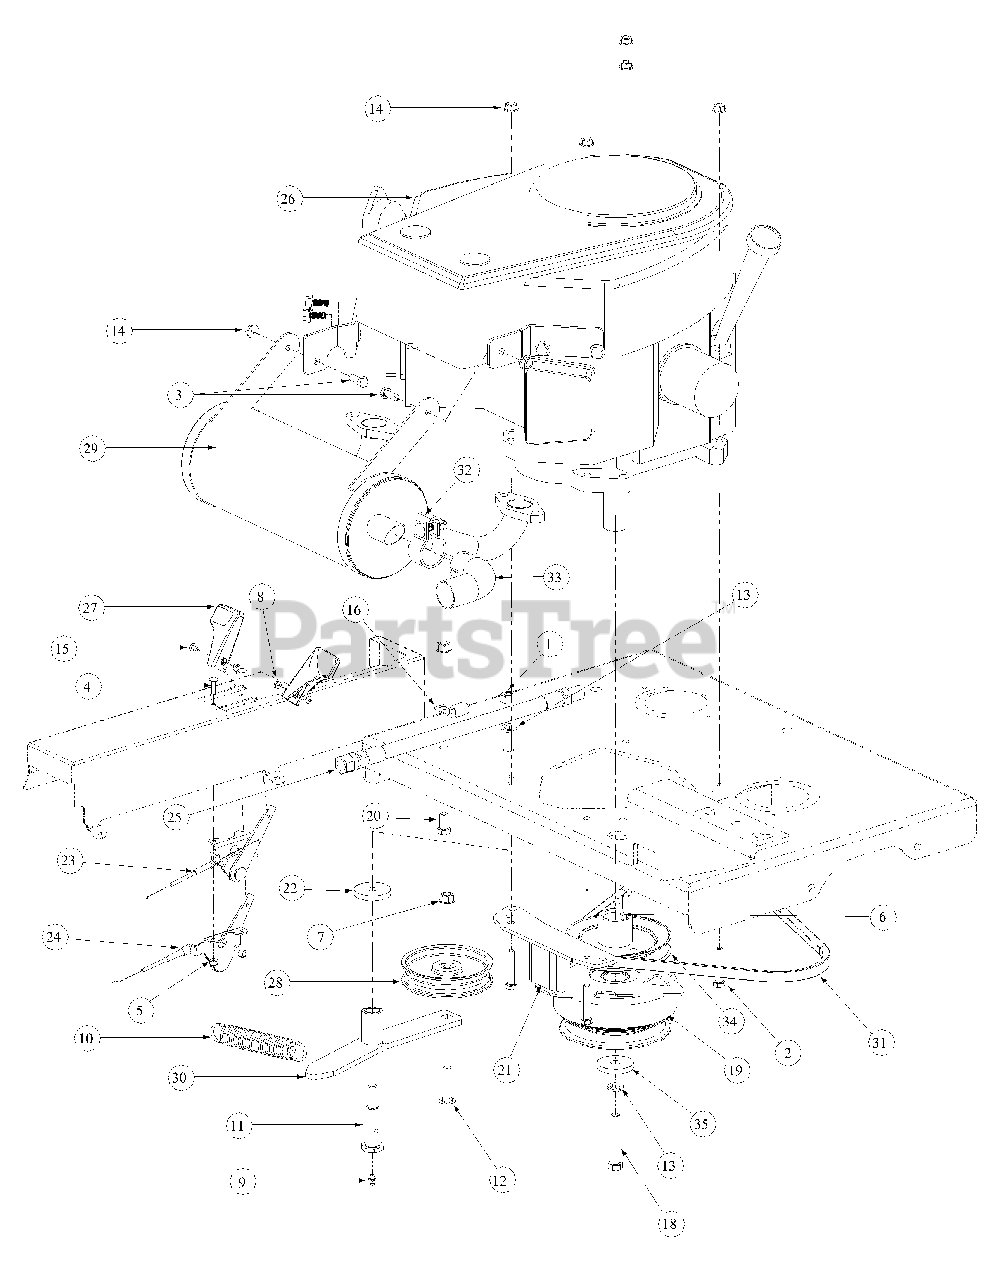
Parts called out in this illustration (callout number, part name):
1	Hex Nut, 7/16-14
2	HHCS, 5/16-18, 1-3/4
3	Hex Cap Screw, 5/16-18 x 3/4
4	Round Hd. Machine Screw, 10-32 x 3/4
5	Lock Nut, Nylon Insert, 10-32
6	Key, 1/4 x 1/4 x 3
7	Flange Lock, Hex Nut, 3/8-16
8	Nut Washer, W/Star, 8-32
9	Grease Fitting, 1/4-28 x 3/16
10	Extension Spring, 1.0 OD x 5.125
11	Shoulder Screw, 7/16-14
12	Hex Carriage Screw, 3/8-16, 1.75
13	Lock Washer, 7/16
14	Hexflange Lock Nut, 5/16-18
15	Machine Screw, 8-32, .375
16	Clip, Heat Shield Cable
18	Capscrew, 7/16-20 x 2.50
19	Clutch Brake, 1.125 ID
20	Hex Cap Screw, 3/8-16, .750
21	Retainer Clutch Assembly, Ogura
22	Flat Washer, 7/16 ID x 1.75 OD x .25
23	Choke, Control Cable, 43.0
24	Throttle, Control Cable, 39.0
25	Oil Drain Hose
26	23HP Kawasaki Engine
27	Control Throttle Knob
28	Flat Pulley with Flanges
29	Muffler Accessory, Kawasaki
30	Engine Idler Arm Assembly includes:
31	V Belt, A Section x .47.3
32	Tube Clamp, 1.375
33	Muffler Accessory Exhaust Tube
34	Pump Drive Pulley
35	Flat Washer, 7/16 ID x 1.75 OD x .25
